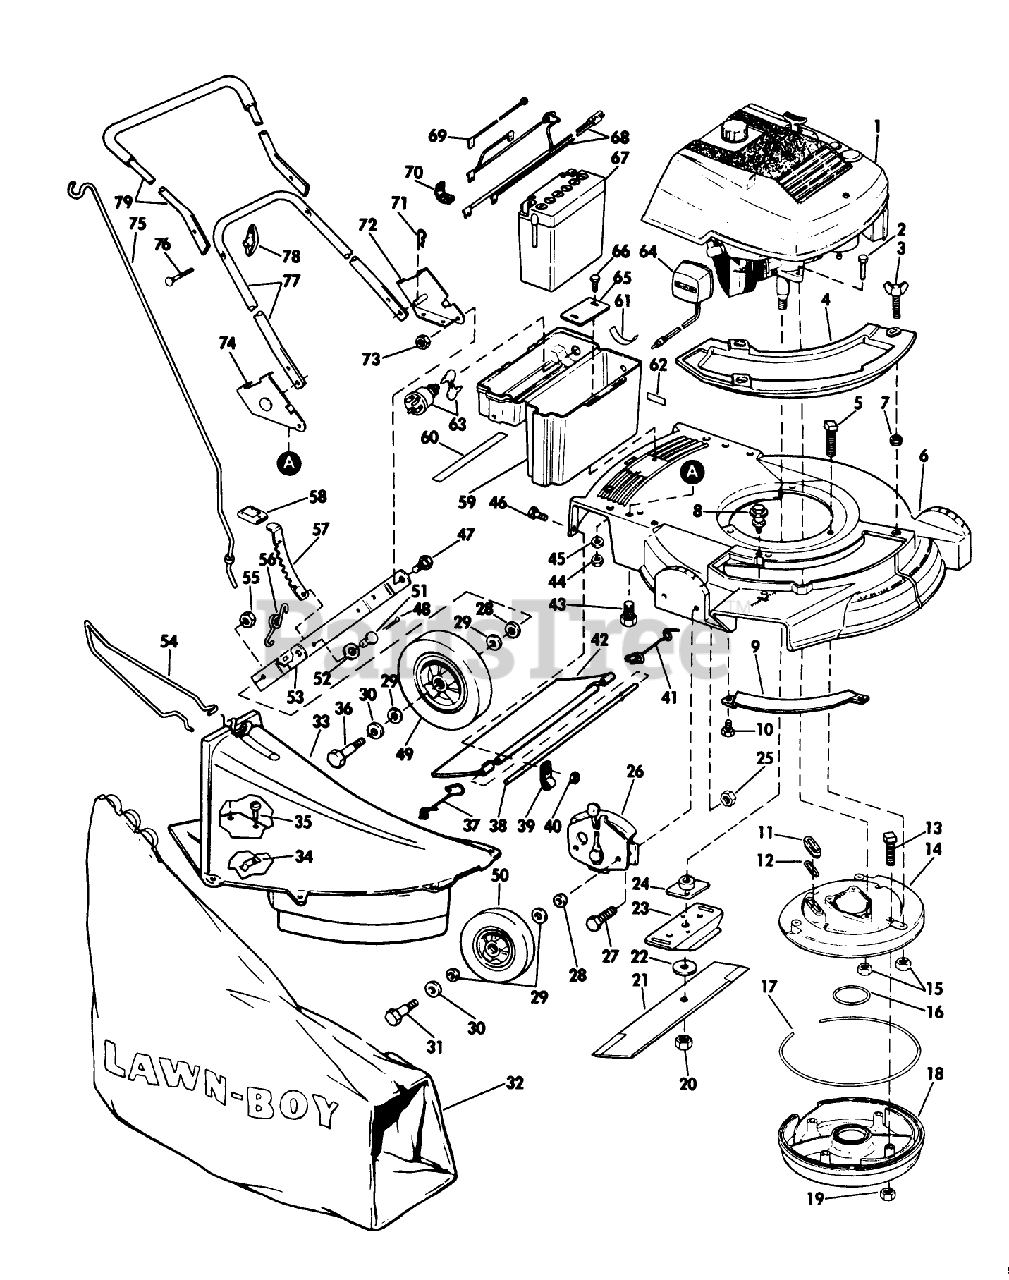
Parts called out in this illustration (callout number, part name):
3	WING SCREW LAWRE
5	SCREW V
9	BAR-TOE
12	GASKET S
15	NUT-LOCK F
17	Gasket Muffler (outside)
19	LOCKNUT E
20	NUT-BLADE
24	PLATE AND COLLAR ASM
28	WASHER WROUGHT
31	BOLT WHEEL
32	ORD LB 89802 WHOLE GOODS
37	SPRING;TRAILING SHIELD RH
38	ROD 21" ADVANCE
39	CLAMP ROD KMC
41	SPRIG T/SHLD ASOC
43	SCREW
47	BOLT-SHOULDER
52	WASHER SPRING LAR
55	LOCKNUT
56	SPRING N.A.S
59	Battery Box Decal Assy.
64	BATTERY CHARGER
71	HAIR PIN
75	ROD GRASSBAG
78	NUT-WING
